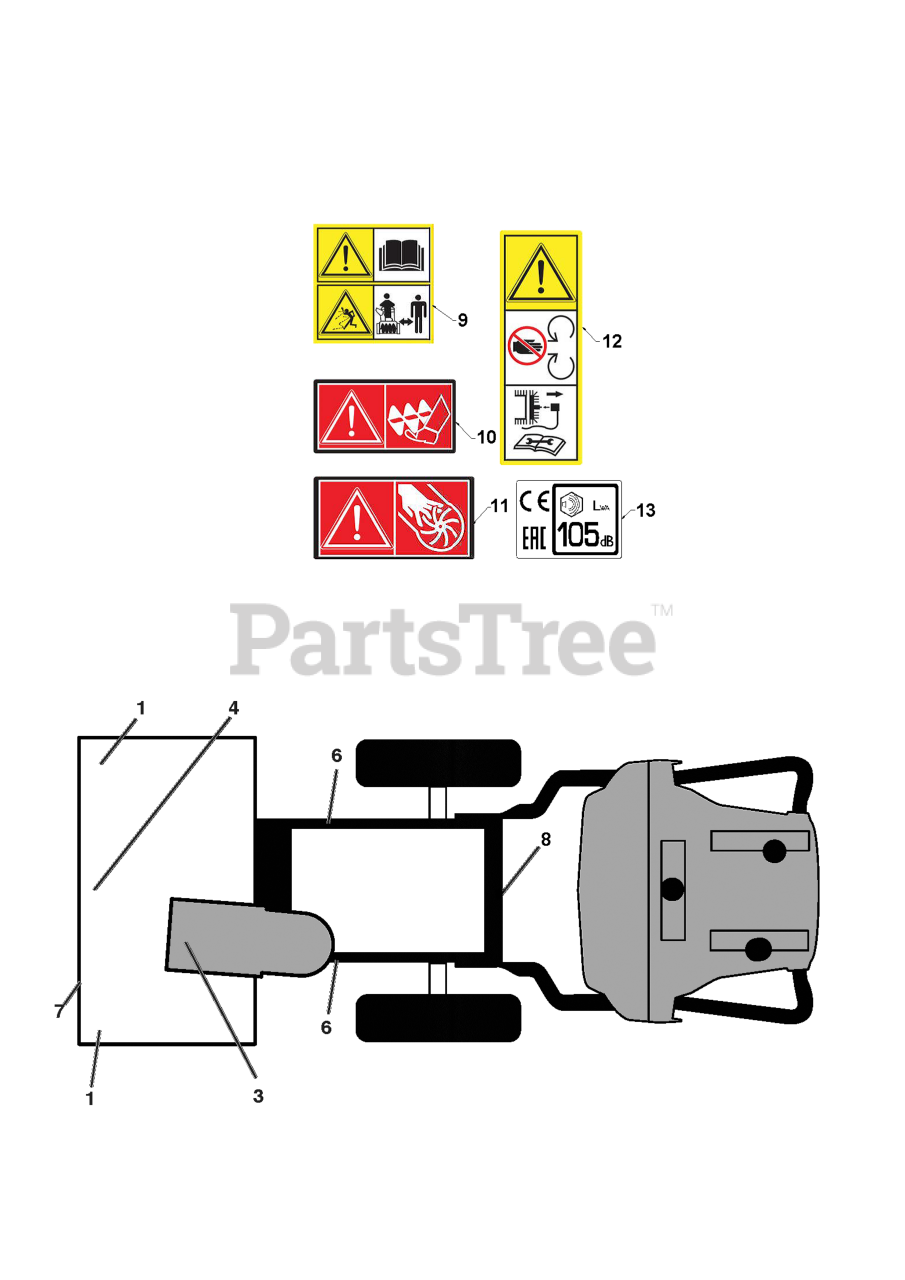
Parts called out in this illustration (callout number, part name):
1	DECAL.AUGER.SAFETY.
3	DECAL.CHUTE.SAFETY.EU/SC.17
3	DECAL.CHUTE.SAFETY.
4	DECAL.AUGER."
6	DECAL.BELT.GUARD.
7	DECAL.AUGER HSG.HUSQ.ST 227P
8	DECAL.NOISE.LEVEL.105DB/CE.EAC
8	DECAL.NOISE.LEV.105/CE.EAC.UKR
9	DECAL.AUGER."
10	DECAL.AUGER.SAFETY.
11	DECAL.CHUTE.SAFETY.
11	DECAL.CHUTE.SAFETY.EU/SC.17
12	DECAL.BELT.GUARD.
13	DECAL.NOISE.LEVEL.105DB/CE.EAC
13	DECAL.NOISE.LEV.105/CE.EAC.UKR
13	DECAL.FENDER.105DB/CE.
